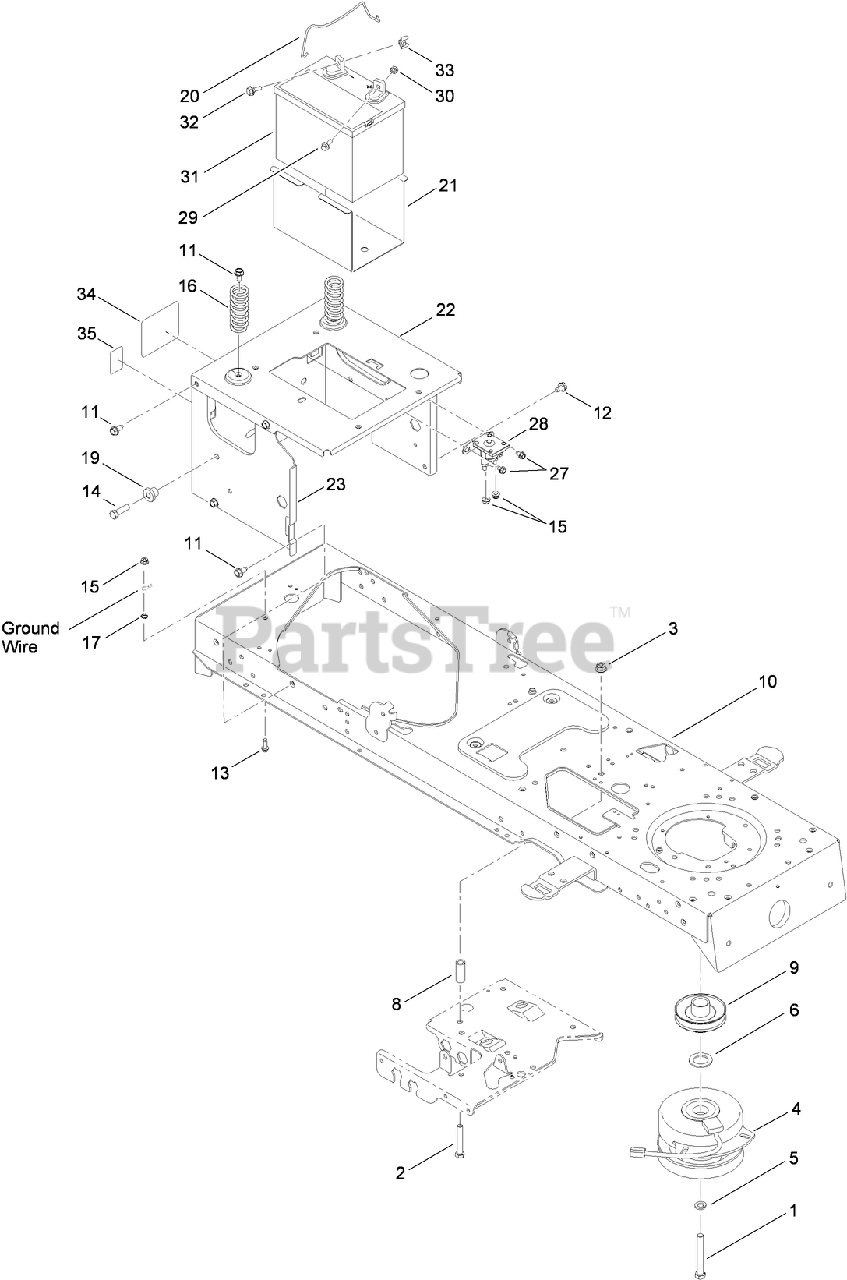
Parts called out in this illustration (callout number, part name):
1	SCREW-HH
2	SCREW-HH
3	NUT-LOCK, FLANGE
4	CLUTCH-ELECTRIC
5	WASHER-LOCK
6	WASHER-FLAT
8	SPACER
9	PULLEY-ENGINE
10	LOWER FRAME ASM
11	SCREW-TAP
12	ROD-SUPPORT
13	SCREW-TAP
14	SCREW-HH
15	NUT-LOCK, FLANGE
16	SPRING-COMPRESSION
17	WASHER-LOCK, EXTERNAL
19	SPACER-SHOULDER
20	ROD-HOLDDOWN, BATTERY
21	TRAY-BATTERY
22	BRACKET-FRAME, SEAT
23	FRAME-UPPER
27	SCREW-HWHTF
28	SOLENOID-12V, 2 POST 2 TAB
29	BOLT-CARRIAGE
30	NUT-SEMS
31	BATTERY-245, CCA,DRY (FLAT TOP)
32	BOLT-SHOULDER
33	NUT-WING, PLASTIC
34	DECAL-TORO
35	DECAL-HYDRO RELEASE
